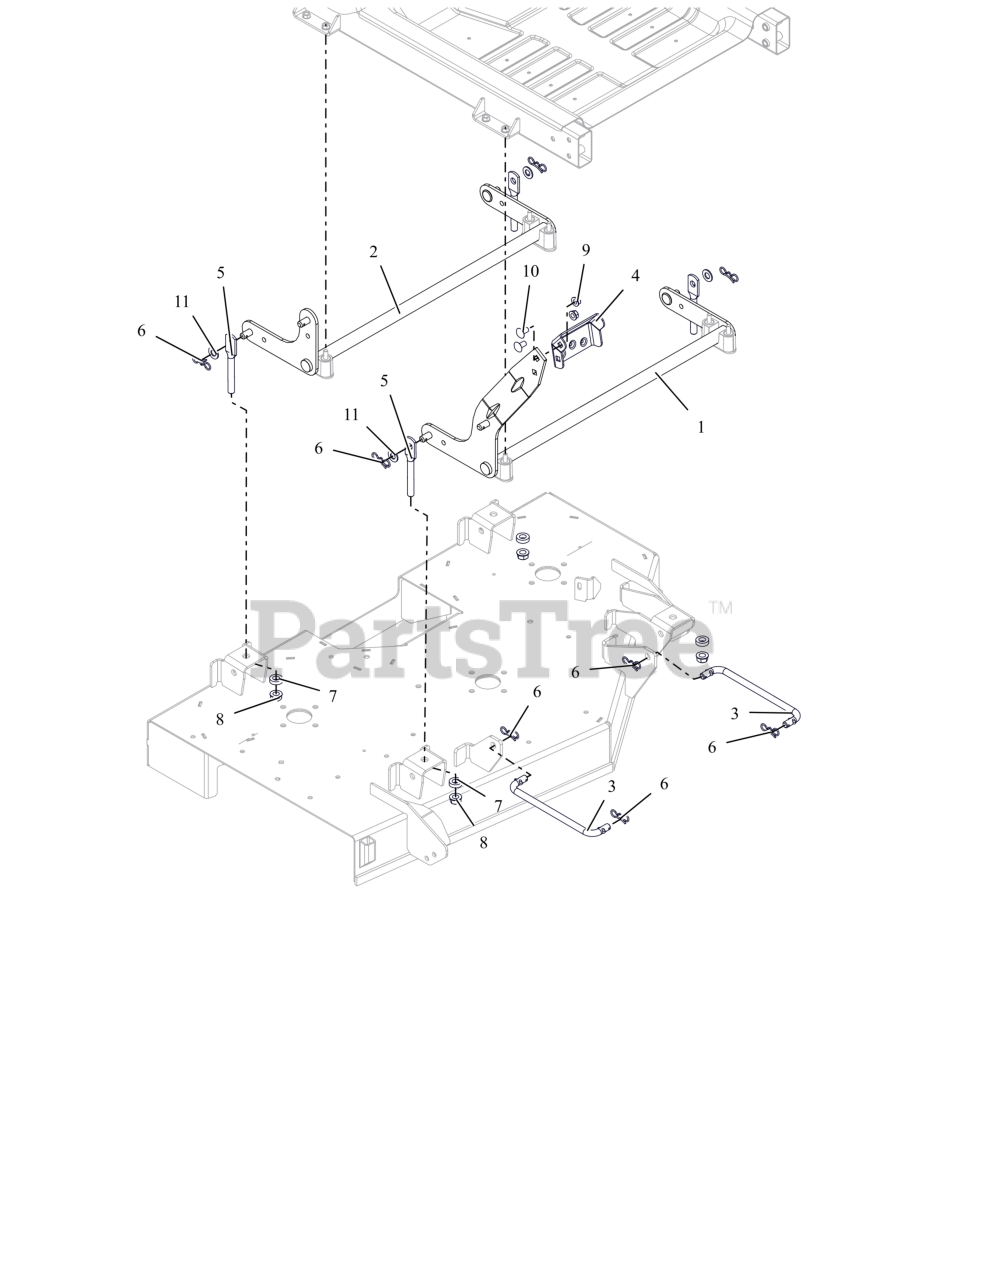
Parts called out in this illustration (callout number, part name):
1	WLDMT, FRONT DECK LIFT PIVOT
2	WLDMT, REAR DECK PIVOT
3	LINK, DRAG
4	PEDAL, DECK LIFT (BOLT ON)
5	LINK,DECK (HOLE-LONG)
6	PIN, BOWTIE .091X1.875 ZCC
7	WASHER, RUBBER
8	NUT-LK-CTR-FLG .500-13 GG ZCC
9	NUT-LK-CTR-FLG .375-16 GF ZCC
10	BTL,RHSSN .375-16 X 0.75 G5 FPB
11	WSHR-FL-NYL .518X1.000X.080
